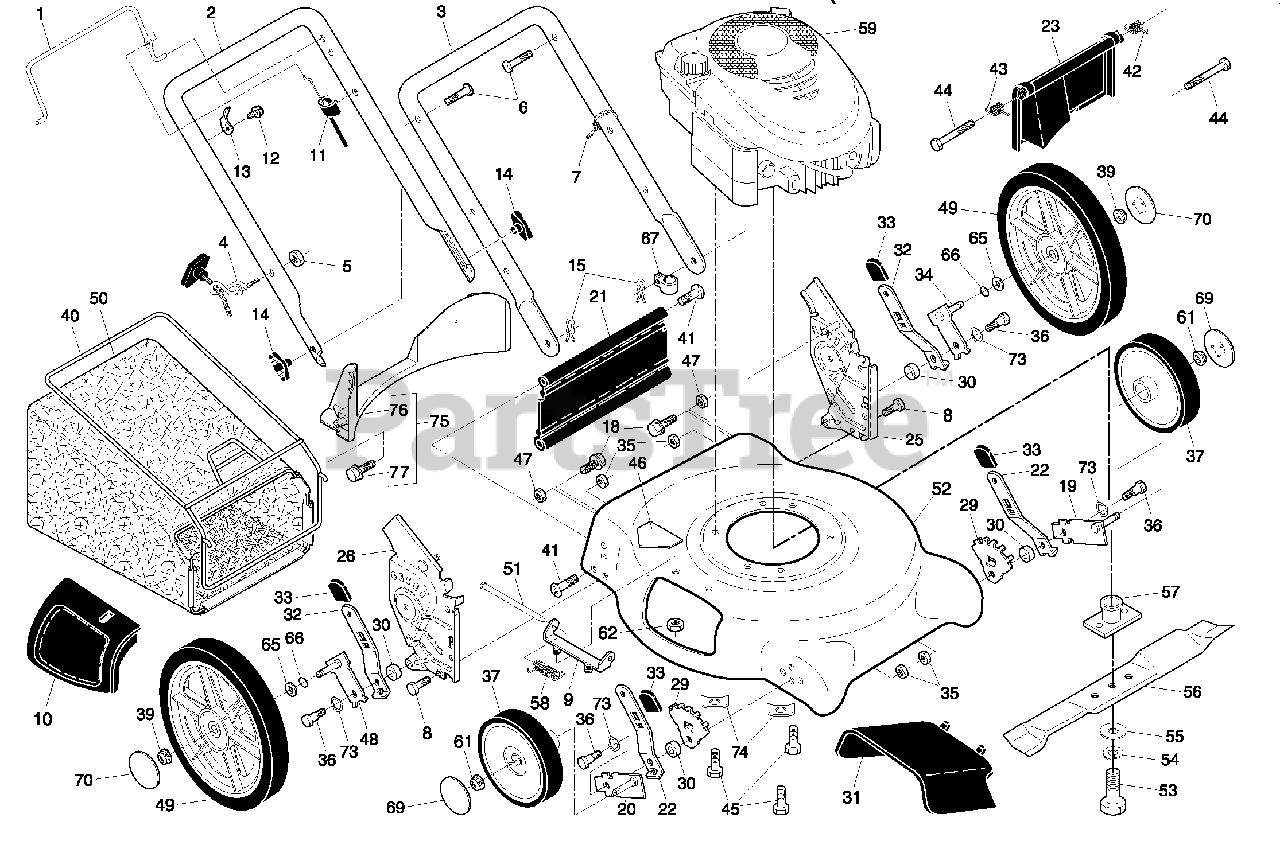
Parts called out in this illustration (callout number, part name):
1	Control Bar
2	Upper Handle
3	Lower Handle
4	Rope Guide
5	Locknut, Hex 1/4-20
6	Handle Bolt
7	Wire Tie
8	Hex Bolt 5/16-18 x 3/4
9	Mounting Bracket, Mulcher Door
10	Mulcher Door
11	Engine Zone Control Cable
12	Hex Washer Head Screw #10-24 x 1/2
13	Up-Stop Bracket
14	Handle Knob
15	Hairpin Cotter
18	Screw
19	Axle Arm Assembly, Front, LH
20	Axle Arm Assembly, Front, RH
21	Kit, Rear Skirt
22	Selector Spring, Front
23	Rear Door Assembly
25	Handle Bracket, LH
26	Handle Bracket, RH
29	Wheel Adjusting Bracket
30	Spacer
31	Deflector, Discharge
32	Selector Spring, Rear
33	Selector Knob
34	Axle Arm Assembly, Rear, LH
35	Locknut, Hex 5/16-18
36	Shoulder Bolt 5/16-18
37	Wheel & Tire Assembly, Front, 8"
39	Flanged Locknut
40	Frame, Grassbag
41	Hinge Screw
42	Spring, Rear Door, LH
43	Spring, Rear Door, RH
44	Bolt, Rear Door
45	Screw, Hex Head Thread Rolling Screw 3/8-16 x 1
46	Danger Decal
47	Nut, Hex
48	Axle Arm Assembly, Rear, RH
49	Wheel & Tire Assembly, Rear, 12"
51	Rod, Hinge
52	Kit, Lawn Mower Housing
53	Hex Head Screw, Grade 3/8-24 x 1-3/8
54	Helical Lockwasher
55	Hardened Washer
56	21" Blade
57	Blade Adapter
58	Spring, Hinge Rod
61	Flanged Locknut
62	Nut, Hex
65	Washer, Flat 3/8
66	O-Ring
67	Clip, Cable
69	Hubcap, Front Wheel
70	Hubcap, Rear Wheel
73	Washer, Curved, Cylindrical
74	Washer, Special, Engine
75	Kit, Rear Baffle
76	Baffle, Rear
77	Screw, Rear Baffle
77	Operator's Manual, English
77	Operator's Manual, French
77	Repair Parts Manual
